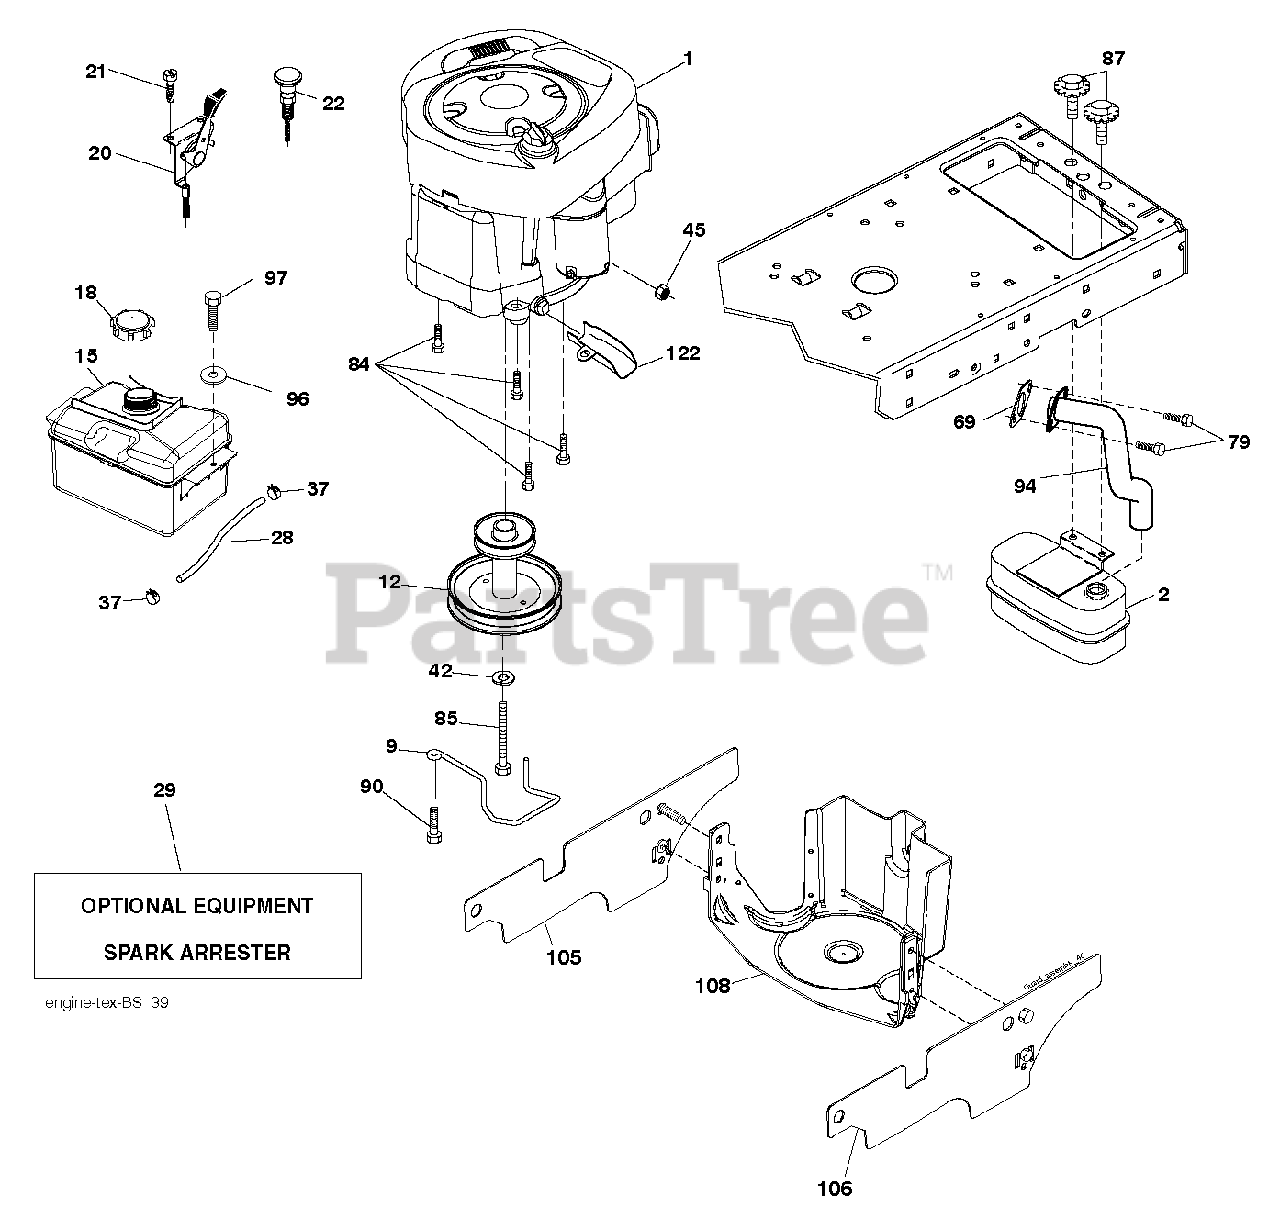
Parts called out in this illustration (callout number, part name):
2	MUFFLER.SINGLE.CYL.KOHL/B&S
9	KEEPER.BELT.ENGINE.4.2
12	PULLY ENGINE
15	TANK FUEL FRT 1.5 GAL
18	CAP ASM.FUEL.2.25"FR.
20	CONTROL.TH/CK.C.
21	SCREW.#10 X 0.750.BOS THREAD
28	LINE.FUEL.20
29	ARRESTER SPARK (OPTIONAL)
37	HOSE CLAMP
42	LOCKWASHER
45	NUT
69	REPL BY 532 27 22-93
79	SCREW.SOCKET HD.5/16-1
84	SCREW.3/8-16
85	BOLT HEX 7/16-20X4-1/4"
87	BOLT, 5/16-18 X 1 3/4
90	SCREW 3/8-16X1
94	EXHAUST.TUBE.B&S.
97	SCREW HEXWSHR 1/4-20X3/4
122	EXTENSION DRAIN OIL
